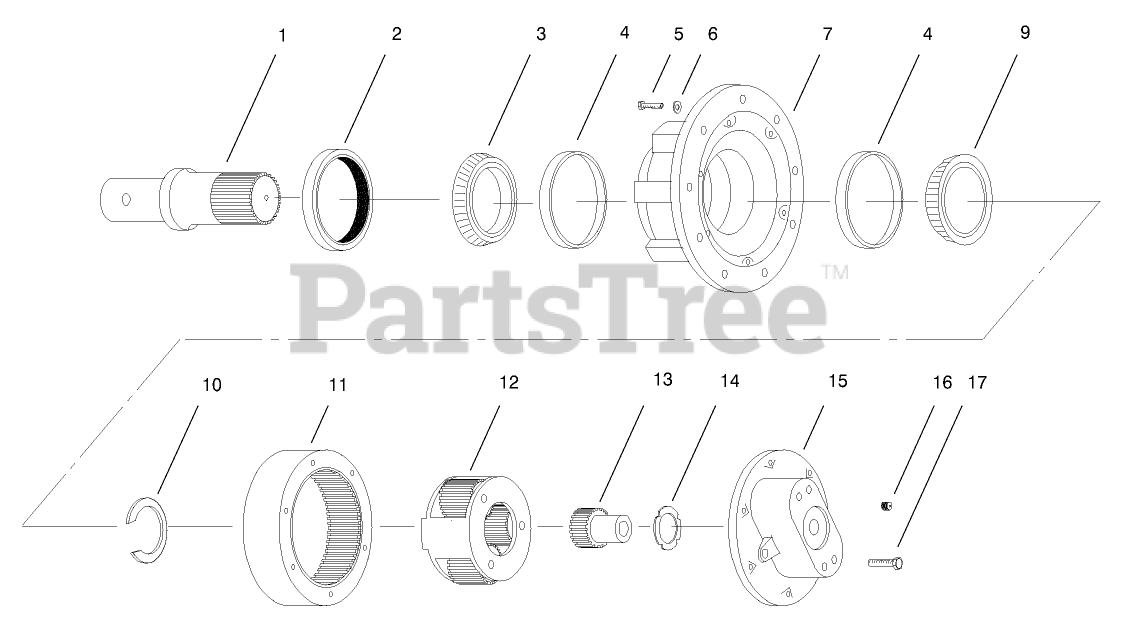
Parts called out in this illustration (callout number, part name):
1	SHAFT - OUTPUT
6	WASHER
7	HUB W/HOLES
10	RETAINING RING KIT
11	GEAR - RING
12	CARRIER ASM
13	GEAR - SUN
14	WASHER
15	COVER
16	PLUG - PIPE, MAGNETIC
